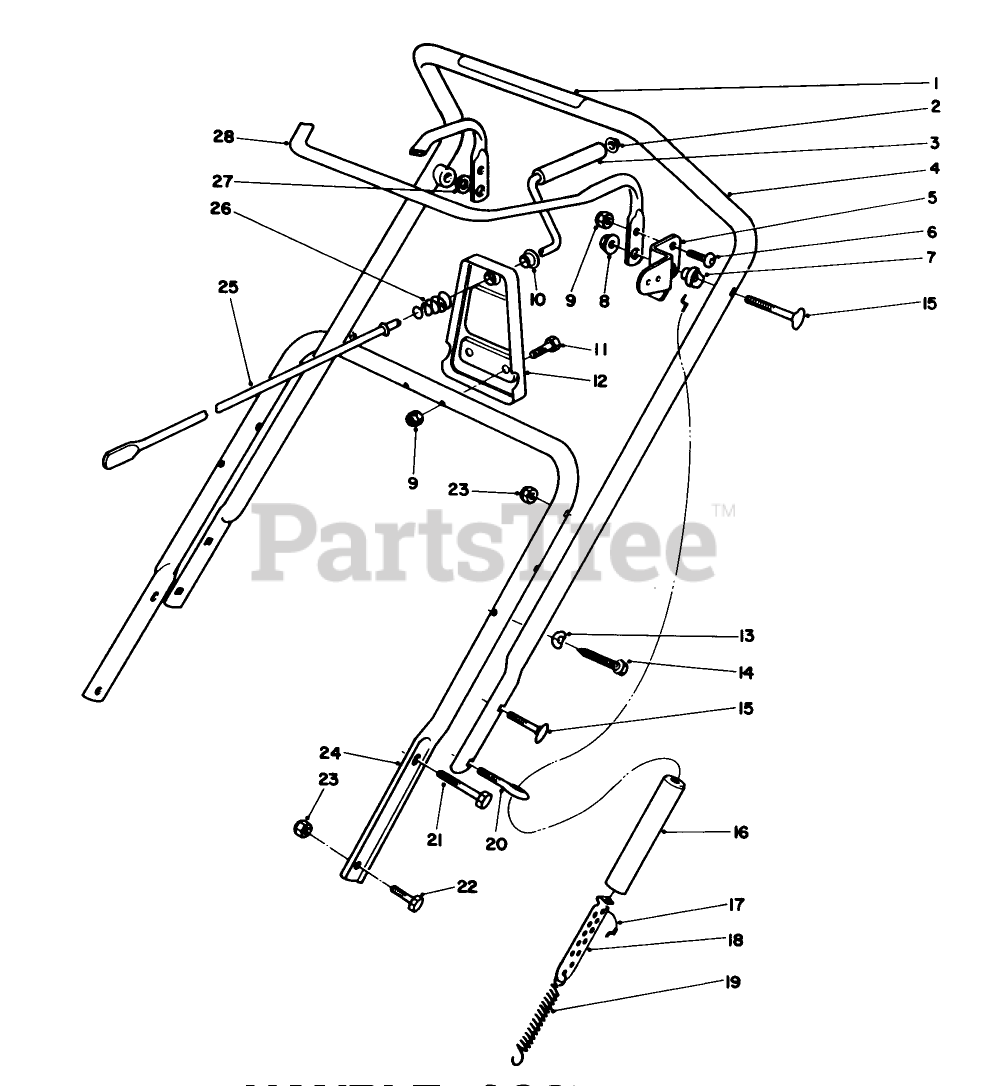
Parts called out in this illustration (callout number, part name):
1	DECAL - ROTOR DRIVE
2	ROTOR DRIVE DECAL
2	RETAINER-PUSH ON
3	Grip-Rod
4	Upper Handle Assembly (Incl. Ref. #1: 66-6870)
5	Arm-Clutch Cable
6	SCREW-HSBH
7	SPACER-BAR, CONTROL
8	NUT-LOCK, CAP
9	NUT-LOCK, NI
10	Bushing
11	SCREW-HH
12	Support-Crank
13	WASHER
14	SCREW
15	SCREW
16	COVER-SPRING
17	CABLE-CLUTCH
18	ADJUSTER-CABLE
19	SPRING-EXTENSION
20	BOLT-EYE
21	SCREW-HH
22	SCREW-HH
23	NUT-LOCK, NI
24	LOWER HANDLE
25	ROD-CRANK, CHUTE
26	SPRING-COMPRESSION
27	WASHER
28	Bar-Control
